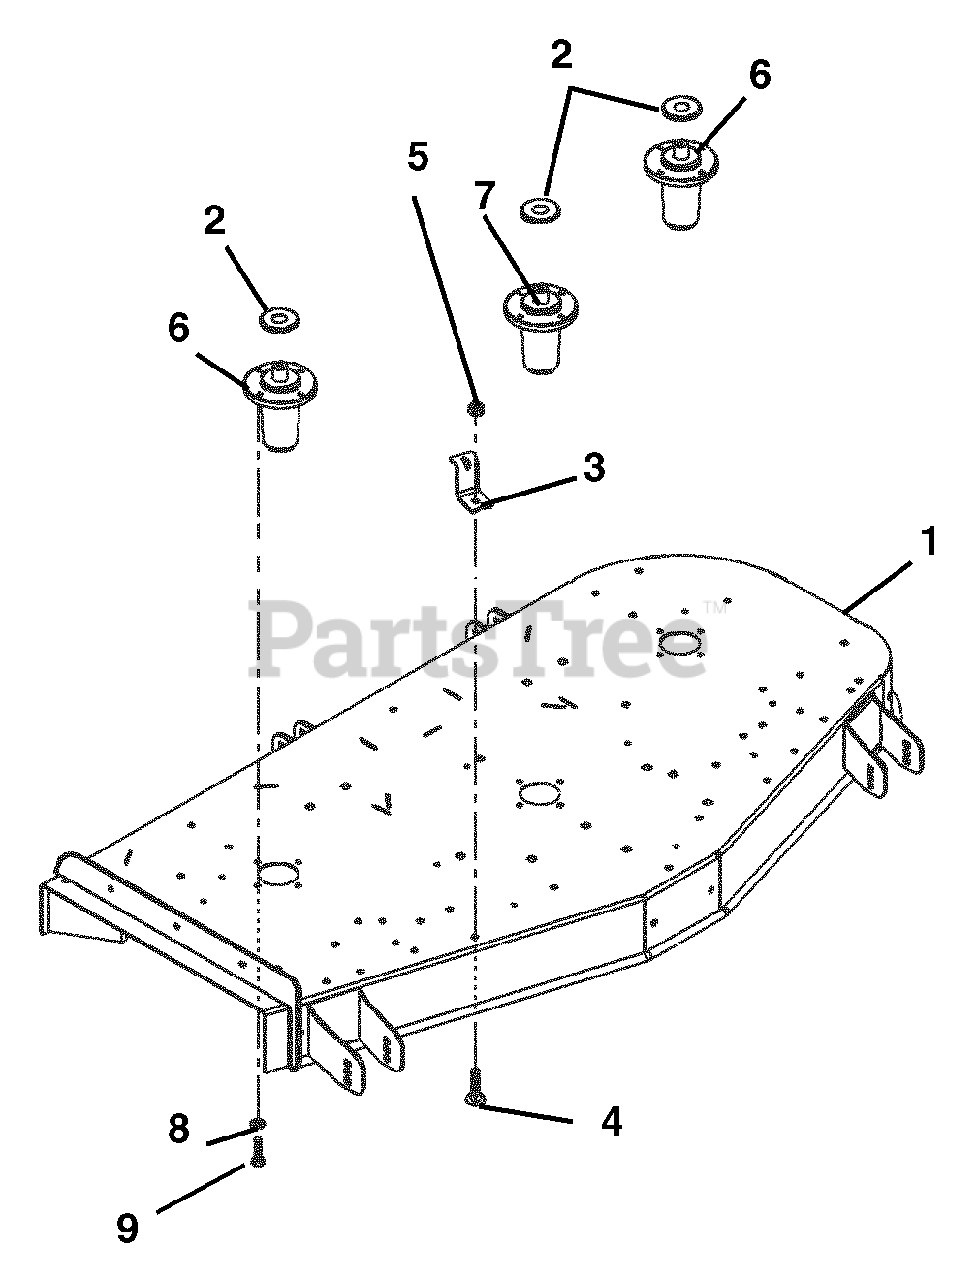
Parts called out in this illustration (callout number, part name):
1	Weldment, 60" Deck (Side Discharge)
2	Slinger-Dust
3	Anchor, Spring
4	Bolt-Round Head Square Neck .38-16 x 1.25 Grade 5
5	Nut-Locking-Nylon .38-16
6	Assembly, Spindle L-Hub
7	Spindle Assembly (Center)
8	Washer-Locking .38 x .094
9	Bolt-Hex .38-16 x 1.00 Grade 5
